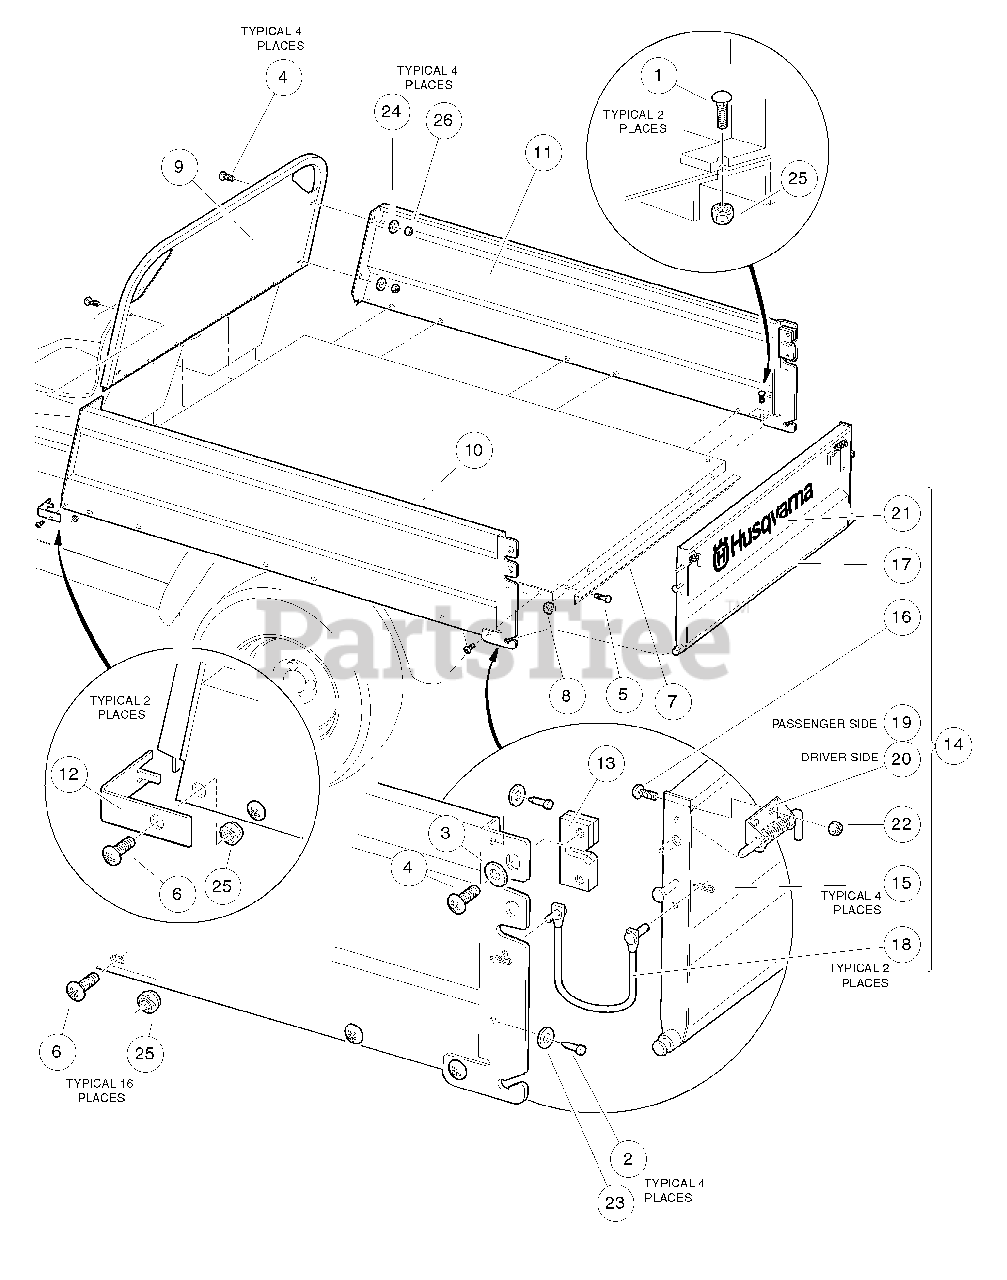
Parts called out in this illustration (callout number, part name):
1	Bolt, Carriage, 5/16-18 X 1.00
2	Bumper, Rubber
3	Washer, 1/4" Type B Flat
4	Screw, 1/4-20 X 0.75 Torx Truss-Head
5	Stud, Self-Clinching Flush Head
6	Screw, 5/16-18 X 0.88 Torx Truss-Head
7	Decal, Bed Load Warning
8	Box Bed Tailgate Angle
9	Locknut, 5/16-18 Hex Flange
10	Front Panel Weldment
11	Left Panel Weldment
12	Right Panel Weldment
13	Front Corner Cap
14	Slam Latch
15	Assembly, Tailgate
16	Hair Pin Clip
17	Screw, 1/4-20 X 0.75 Torx Truss-Head
18	Tailgate, Weldment
19	Tether Assembly
20	Spring Latch Left
21	Spring Latch Right
22	Decal, Husqvarna, Tailgate
23	Locknut, 1/4-20 Nylon Insert
24	Washer, Rubber, 3/8
25	Washer, 1/4 Type A Narrow Flat
26	Locknut, 5/16-18 Nylon Insert
27	Locknut, 1/4-20 Nylon Insert
